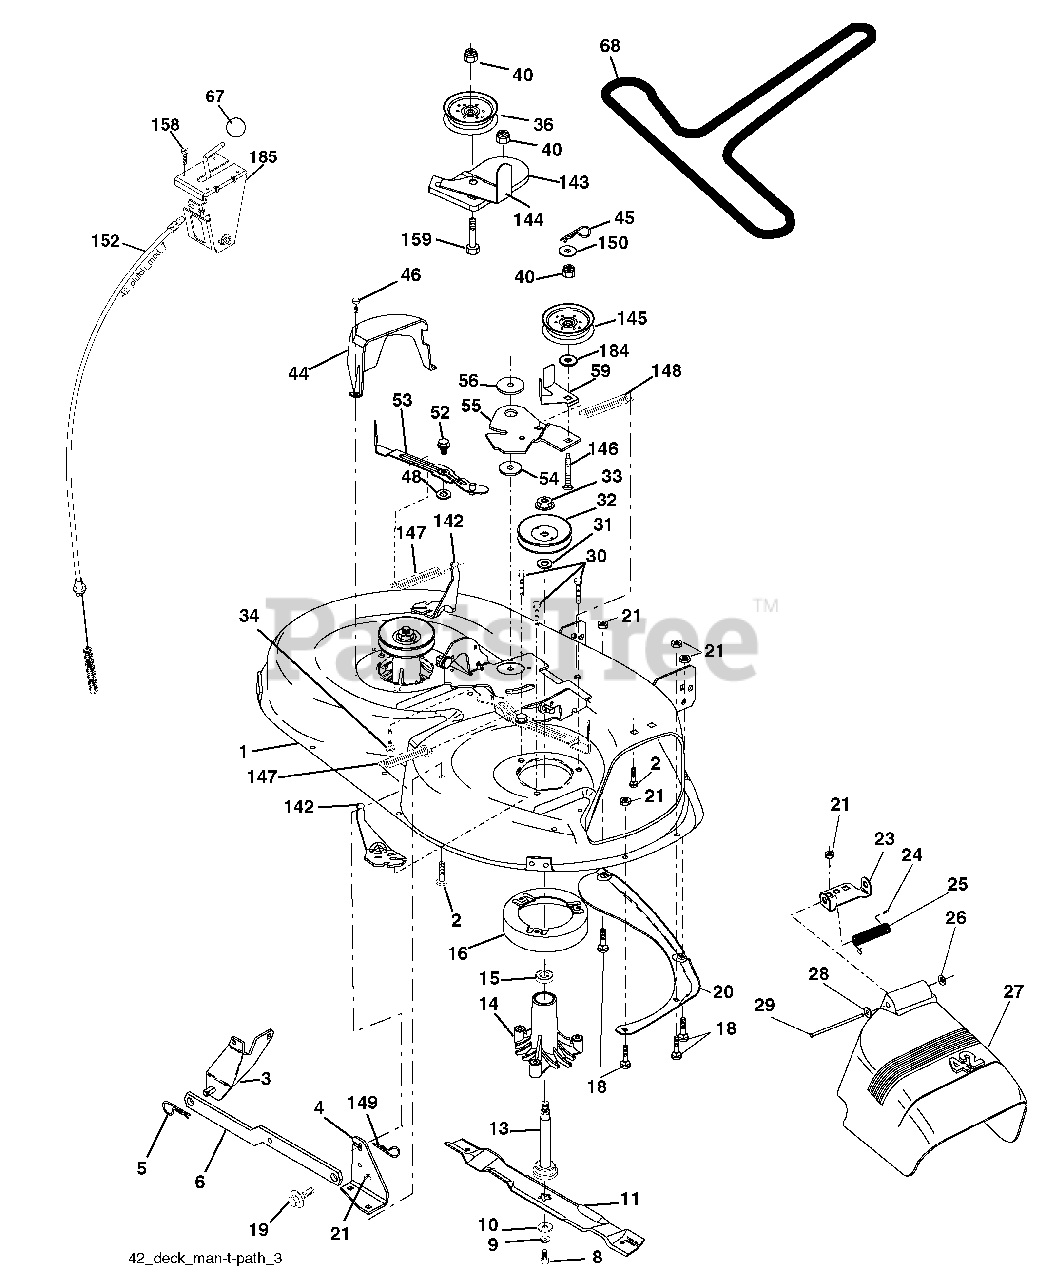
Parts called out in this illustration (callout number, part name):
1	Mower Deck Assembly, 42"
2	Bolt
3	Bracket Asm Fr. Sway Bar 3/42
4	Bracket Asm Deck 42" Sway Bar
5	Retainer Spring
6	Bar Sway Deck
8	Bolt 3/8-24 x 25 Gr. 8 patched
9	Washer, Lock
10	Washer, Hardened (The following blades are available)
11	Blade, 42" Hi-Lift (For bagging or discharging)
11	Blade, 42" Mulching Std (For mulching mowers only)
11	Blade, 42" Mulching Premium (For better wear when mulching)
13	Shaft As sem bly, Mandrel, Vented
14	Housing, Mandrel, Vented
15	Bearing, Ball, Mandrel
16	Stripper, Mandrel Deck
18	Bolt, Carriage 5/16-18 x 5/8
19	Bolt, Shoulder
20	Baffle, Vortex
21	Nut
23	Bracket, Deflector Mower 42"
24	Cap, Sleeve 80 x 112 Blk Mower
25	Spring, Torsion, Deflector 2 52
26	Nut, Push Phos & Oil
27	Shield, Deflector 42" Blk
28	Washer 11/32 x 5/8 x 16 Ga.
29	Rod, Hinge 42" 6 75 W/G
30	Screw Thdrol Washer Head
31	Washer, Spacer Mower Vented
32	Pulley, Mandrel
33	Nut, Toplock Flange
34	Bolt
